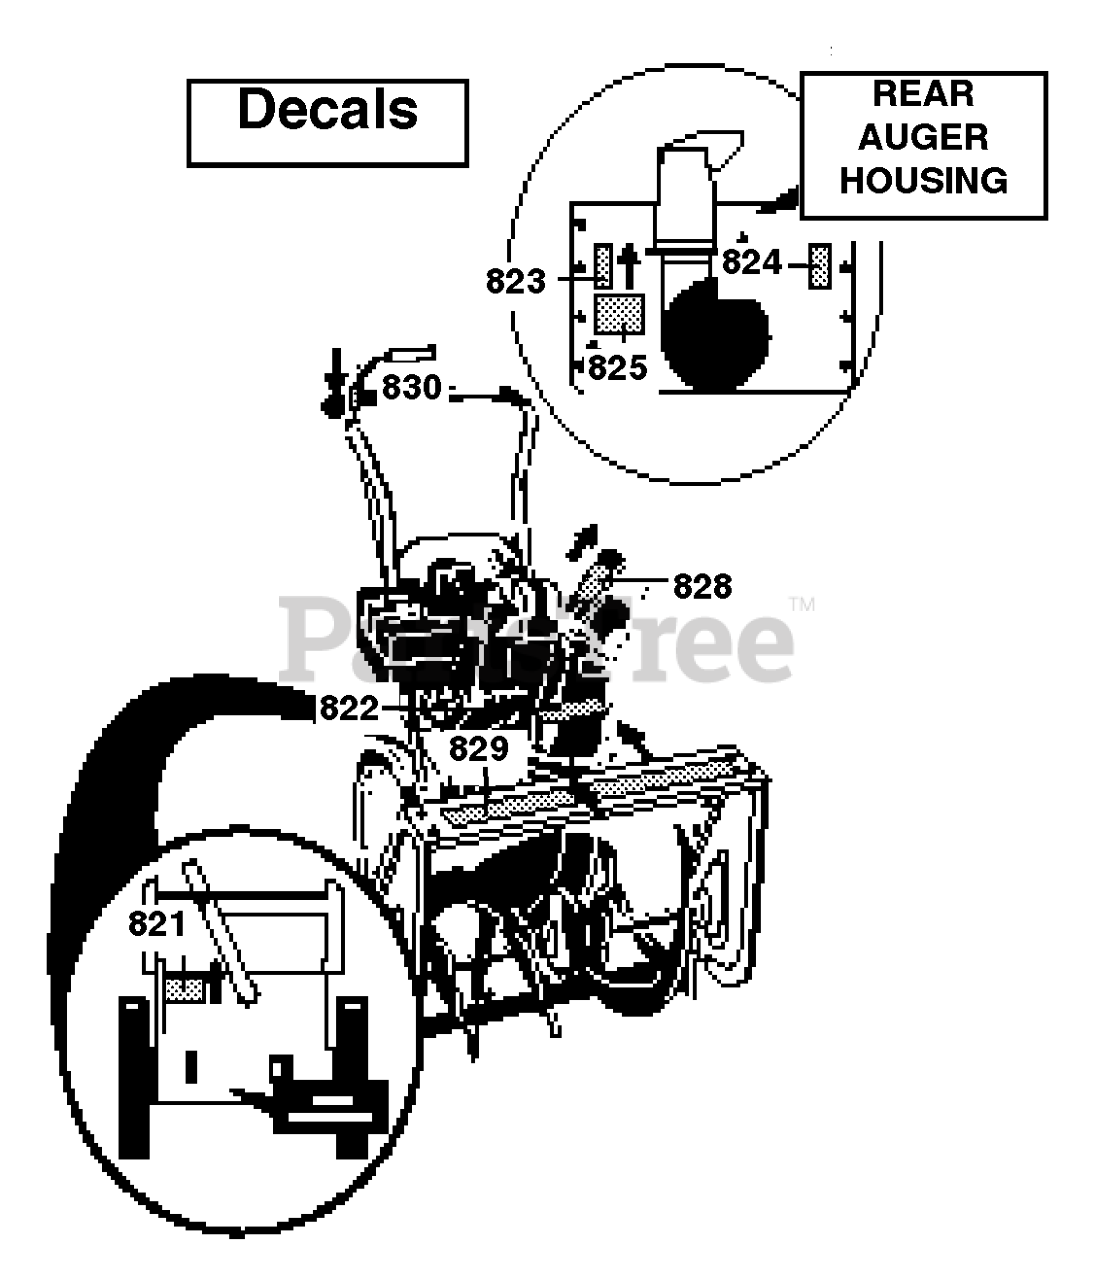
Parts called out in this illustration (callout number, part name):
822	Decal, 9" Impeller
823	Decal, Danger Chute
824	DECAL-DANGER AUGER/FOOT
825	Decal, Danger English
828	Decal, Husq. Crown
829	Decal, ST522H
830	SCREW, 1/4-20X .75 HHC
